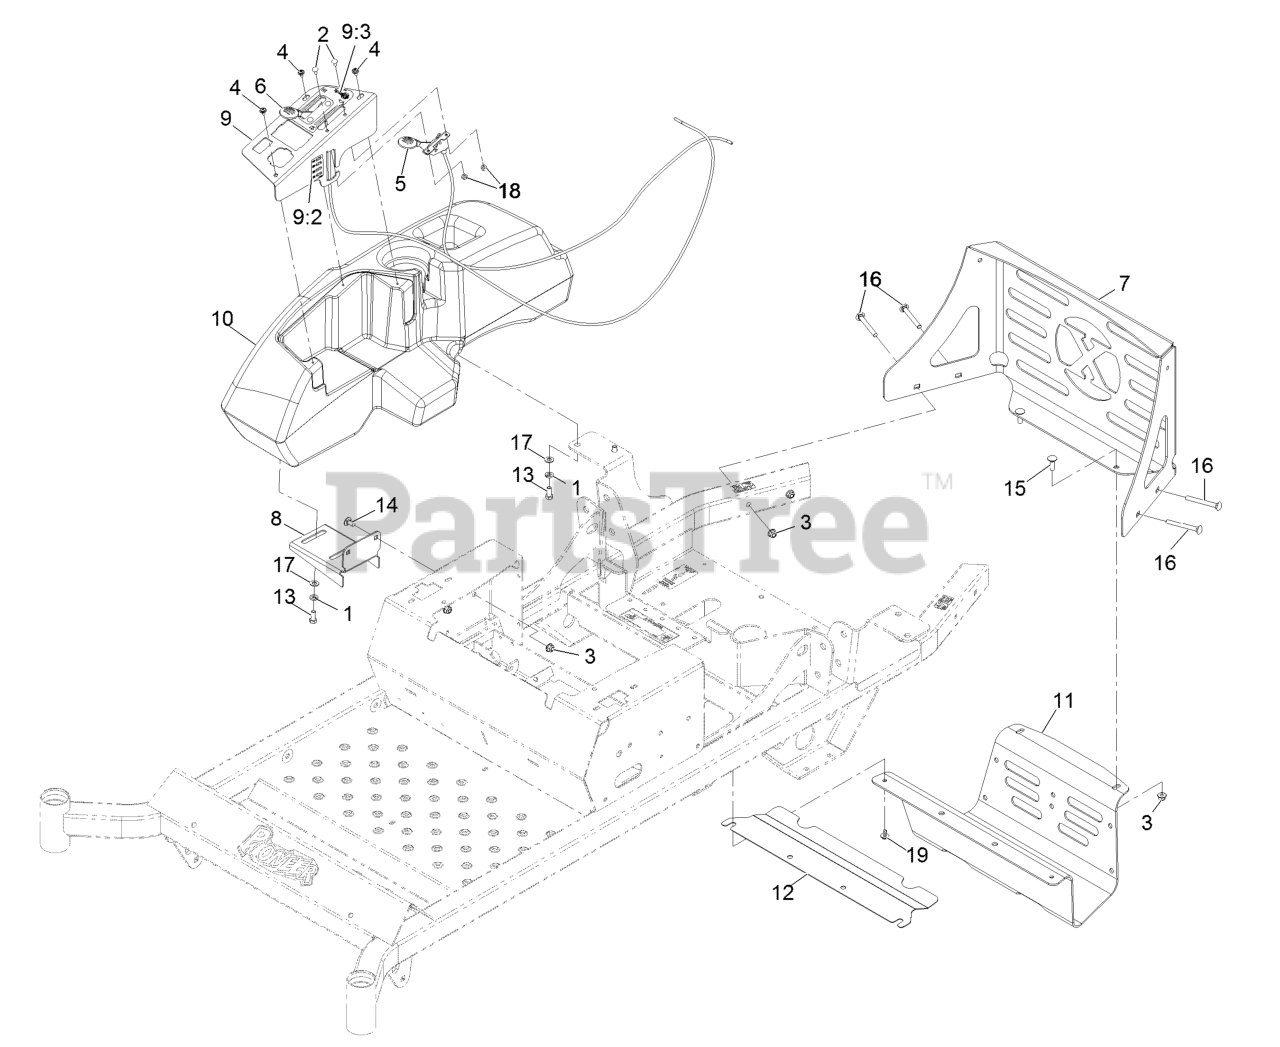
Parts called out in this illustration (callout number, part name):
1	WASHER-LOCK
2	BOLT-CARR
3	NUT-HF, NI
4	SCREW-PPH
5	CONTROL,THROTTLE
6	CONTROL,CHOKE
7	PANEL,REAR GUARD
8	BRACKET-TANK AND FENDER
9	ASM,CONTROL PANEL W/DECAL
9:2	DECAL,FUSE BLOCK
9:3	DECAL-THROTTLE CHOKE
10	CONSOLE,RH
11	GUARD-MUFFLER
12	SHIELD, HEAT
13	SCREW-HH
14	SCREW-CARR
15	BOLT-CARR
16	SCREW-CARR
17	WASHER-PLAIN
18	NUT-LOCK, NI
19	SCREW-HHFTF
